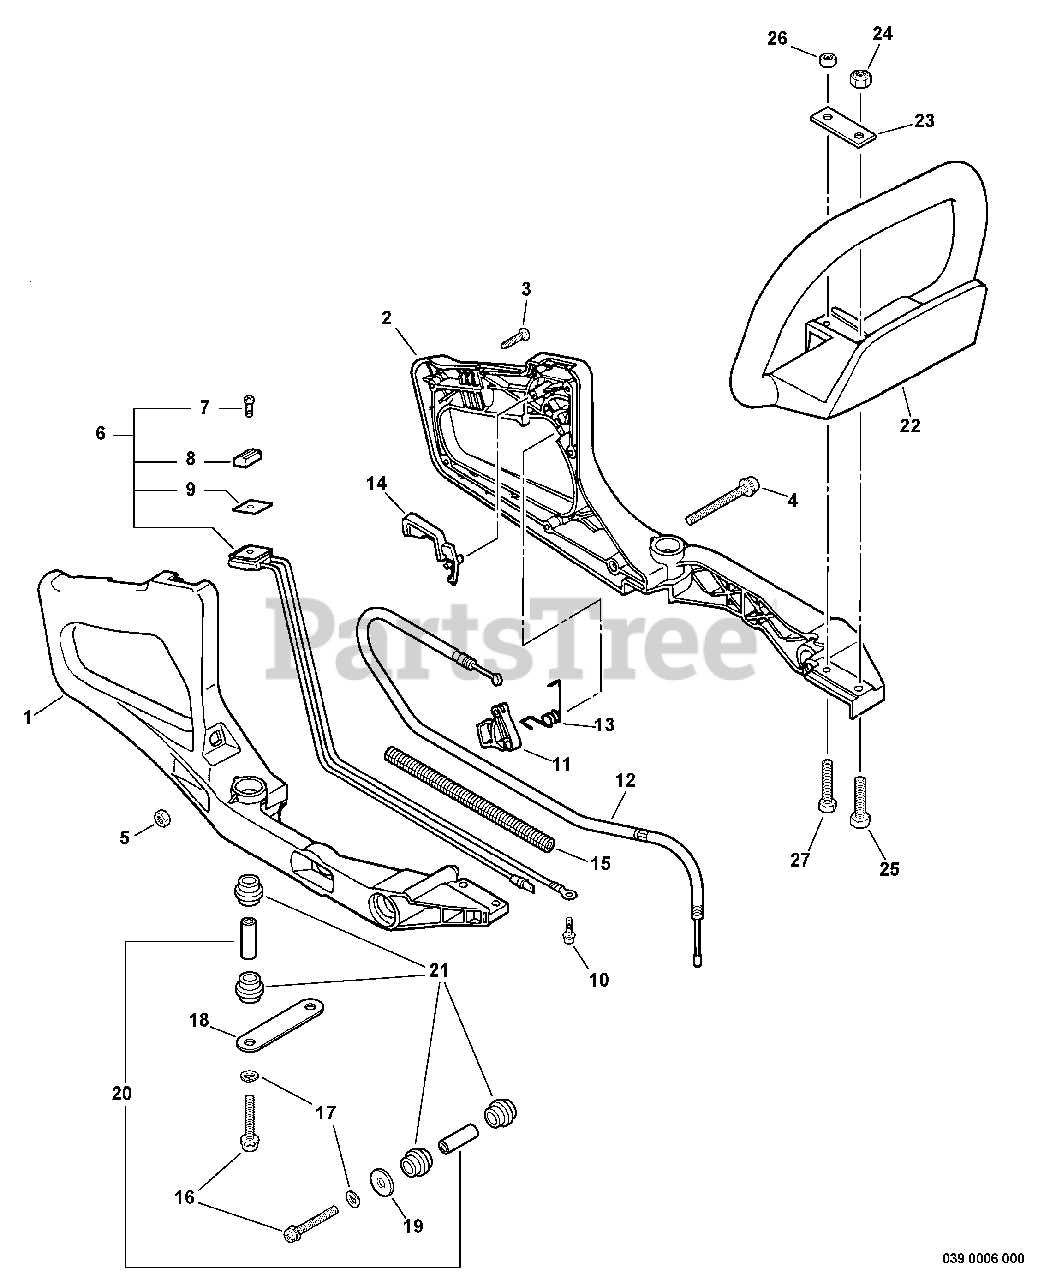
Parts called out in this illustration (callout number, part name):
1	HANDLE, REAR - RIGHT
2	HANDLE, REAR - LEFT
3	SCREW - 4X25
4	SCREW - 5X64
6	IGNITION SWITCH ASSY
7	SCREW - 3X10
8	KNOB, SWITCH - ORANGE
9	COVER, SWITCH - STOP
10	SCREW - 5X10
11	TRIGGER, THROTTLE
12	CABLE, THROTTLE
13	SPRING, LOCKOUT LEVER
14	LOCKOUT, THROTTLE
16	SCREW - 5X40
17	LOCKWASHER - 5
20	SPACER
22	HANDLE - FRONT
24	LOCKNUT - 6
25	BOLT - 6X32
27	BOLT - 5X35
